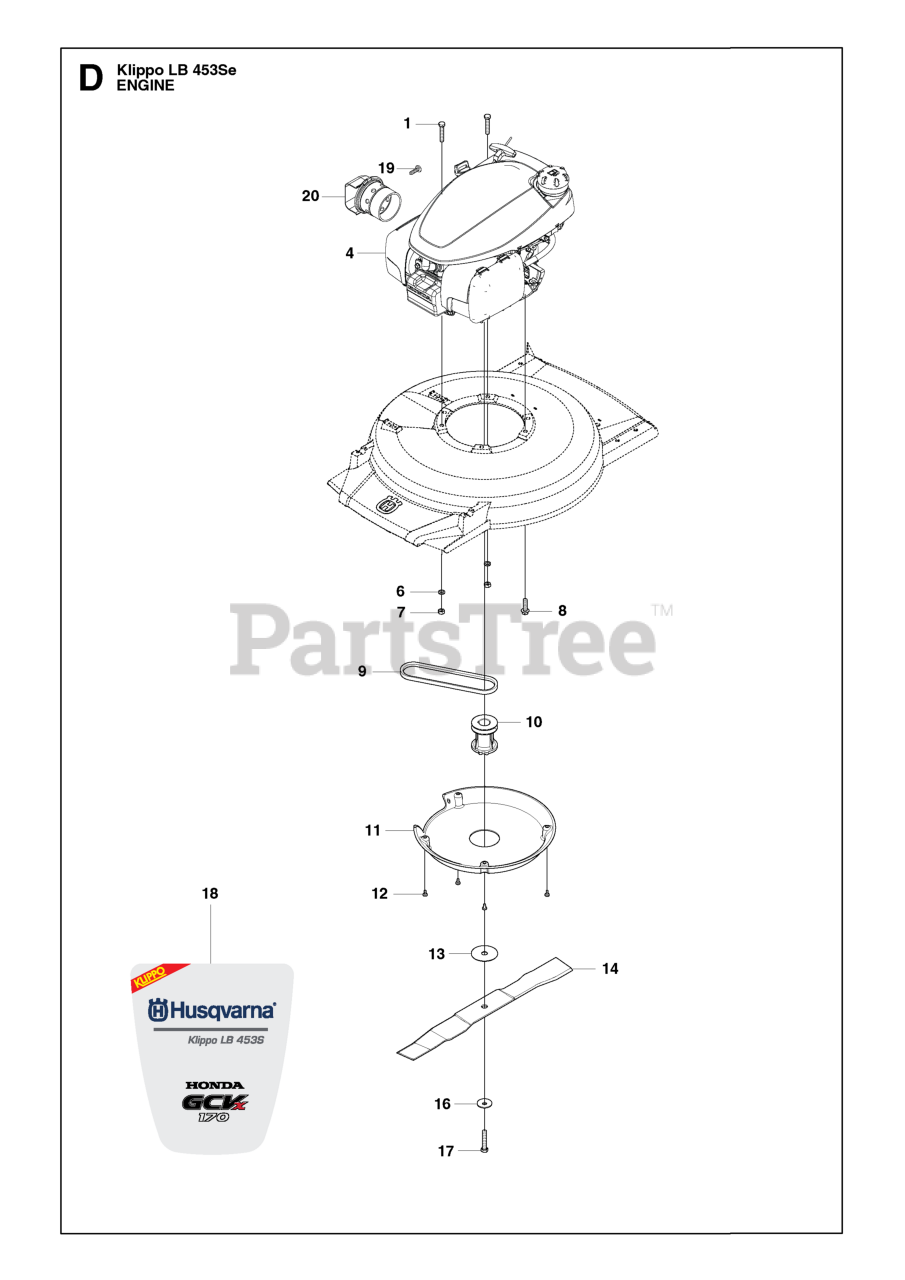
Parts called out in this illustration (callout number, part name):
1	ACCESSORY BAG
2	SCREW IHSCFMO
3	CLAMP ASSY
5	BLADE GUARD
6	SCREW
7	LOCKING NUT
8	TRIMMER GUARD ASSEMBLY
10	LINE CUTTER
11	GRASS SHIELD
13	LINE CUTTER
